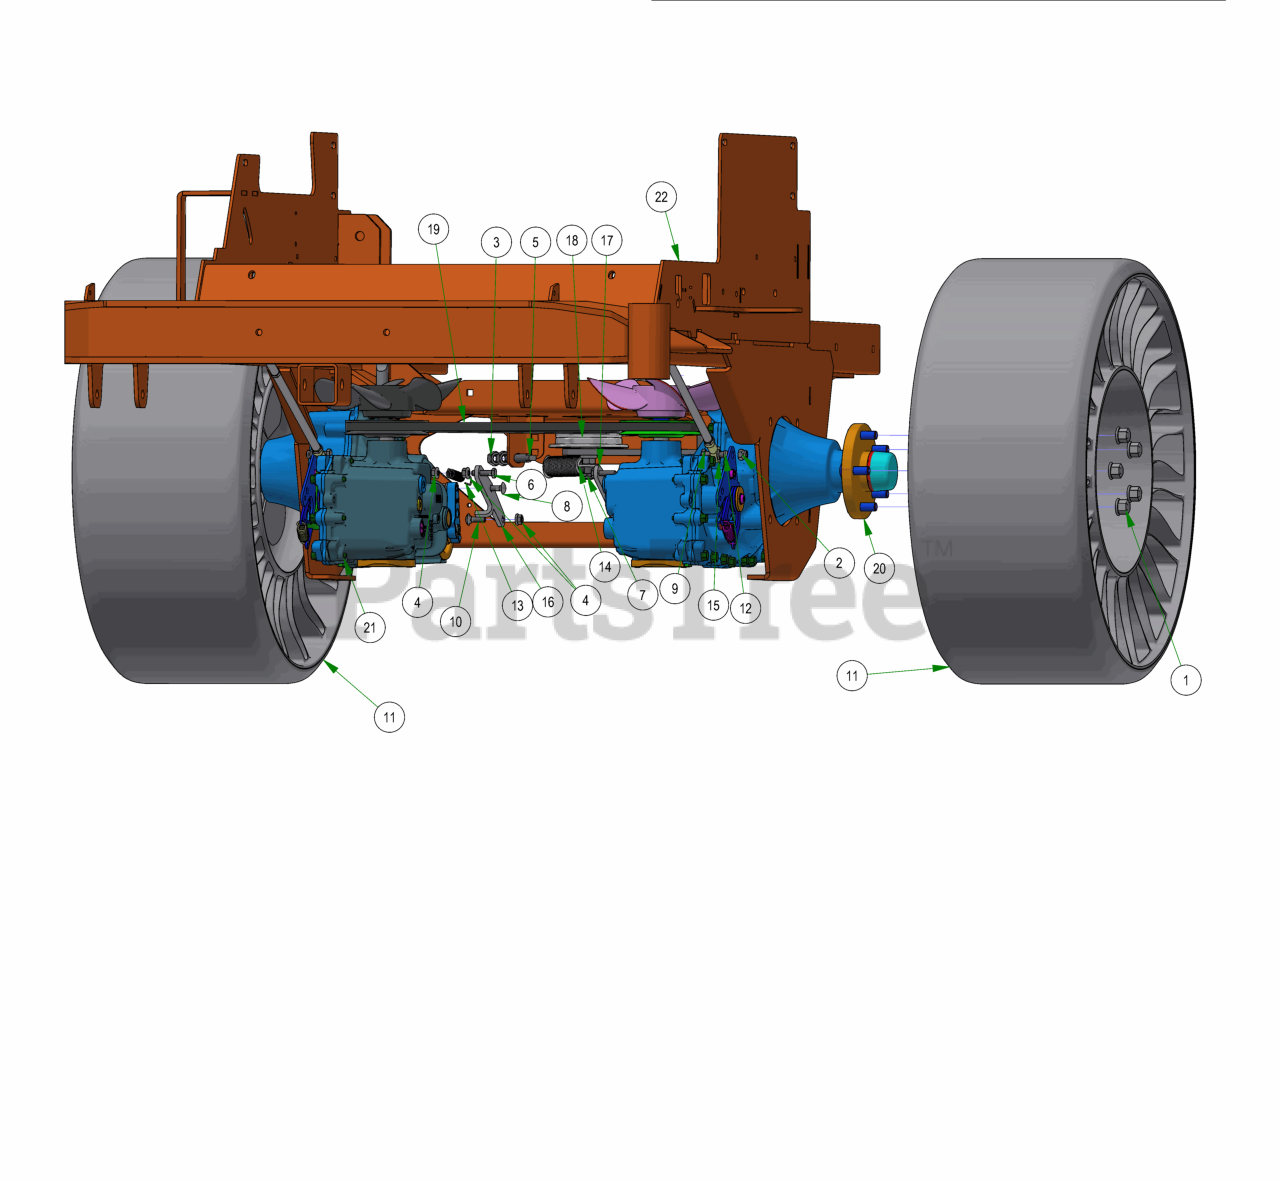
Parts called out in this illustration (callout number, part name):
1	Acorn Lug Nut
2	3/8-16 NYLON INSERT LOCKNUT ZINC
3	1/2-13 HEX NUT ZINC
4	5/16-18 NYLON INSERT FLANGE LOCKNUT ZINC
5	All Thread
6	5/16-18 X 1-1/4 HEX C/S (GR.5) ZC
7	1/2-13 NYLON INSERT JAM LOCKNUT ZINC
8	5/16-18 X 1-1/4 CARRIAGE BOLT ZINC
9	3/8-16 X 1-1/4 HEX CAP SCREW (GR.5) ZINC
10	5/16-18 X 1 CARRIAGE BOLT (GR.8) ZINC
11	TWEEL, 24X12N12 ZTR 5ON4.5 BLACK 1.3IN OFFSET
12	Drive Arm Transaxle Spacer
13	Brake Spring
14	Deck spring big diameter
15	2024 Rebel Push Rod Assembly
16	5400 Transaxle Brake Adapter Plate RH v3
17	5400 Transaxle Brake Adapter Plate LH v3
18	2024 Rebel X Pump Idler
19	2019 Rebel Pump Belt
20	5400 TRANSAXLE LH
21	5400 TRANSAXLE RH
22	2023 Rebel Frame - Painted
